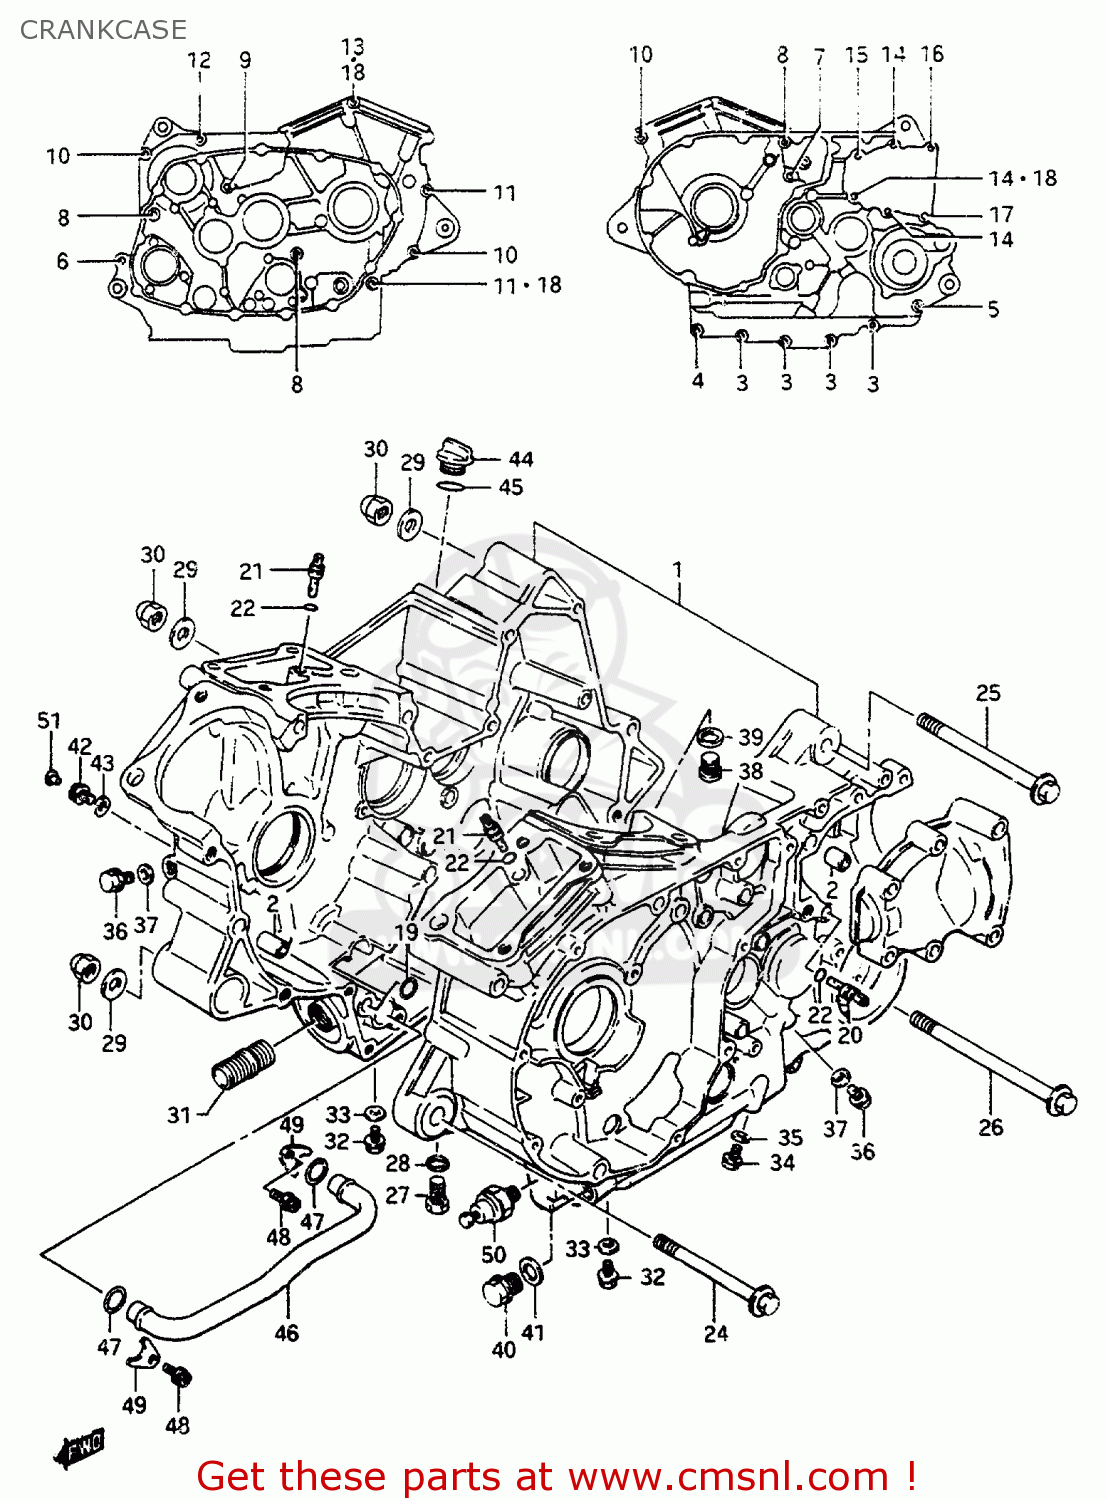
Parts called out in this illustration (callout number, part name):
1	CRANKCASE SET
2	PIN(8.4X11X20)
3	BOLT
4	BOLT
5	BOLT
6	BOLT
7	BOLT
8	BOLT
9	BOLT(8X120)
10	BOLT(8X95)
11	BOLT(8X105)
12	BOLT(8X120)
13	BOLT(8X160)
14	BOLT
15	BOLT
16	BOLT(8X55)
17	BOLT(8X65)
18	GASKET 8.2X14X1 (NAS)
19	O RING(D:1.9,ID:12.6)
20	JET,OIL GALLERY
21	JET,AIR(14)
22	O RING(D:1.2,ID:4)
23	WASHER(48.1X64X1.94)
24	BOLT(10X125)
25	BOLT(10X130)
26	BOLT(10X150)
27	BOLT
28	GASKET(12.1X16.2X3.7) (NAS)
29	WASHER
30	NUT
31	UNION,OIL STAND
32	BOLT
33	GASKET(8.2X14X1).6 (NAS)
34	PLUG(10X12)
35	GASKET(10X14X3.6) (NAS)
36	BOLT
37	GASKET(5.8X13X1.2) (NAS)
38	PLUG
39	GASKET(16X22X2) (NAS)
40	PLUG(14X12)
41	GASKET(14X19.2X2) (NAS)
42	BOLT
43	GASKET(8.2X14X1).6 (NAS)
44	PLUG(20X10)
45	O RING(D:3.1,ID:16.8)
46	PIPE,OIL GALLERY
47	O RING(D:3.1,ID:14.8)
48	BOLT
49	CLAMP,OIL PIPE
50	SWITCH ASSEMBLY,OIL PRESSURE
51	CAP(OD:11)
